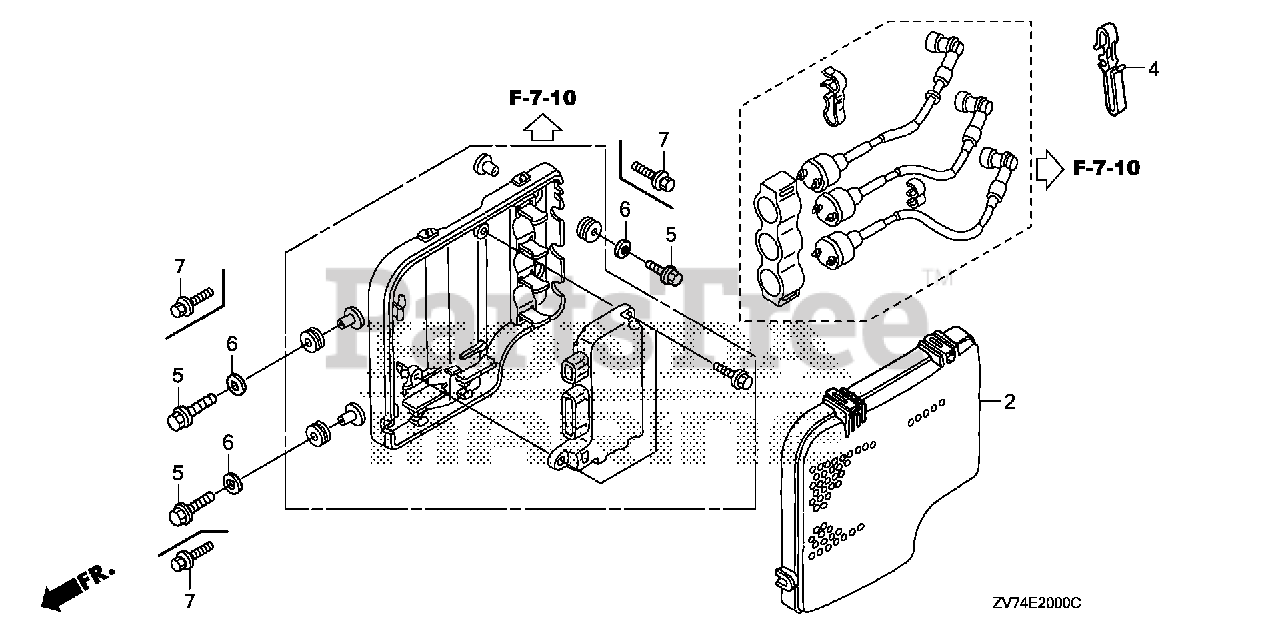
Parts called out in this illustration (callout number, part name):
2	COVER, IGNITION CONTROL MODULE (CDI)
4	CLAMP, CENTER WIRE
5	BOLT, FLANGE (6X25)
6	WASHER, PLAIN (6MM)
7	BOLT-WASHER (6X27) (CT200)
